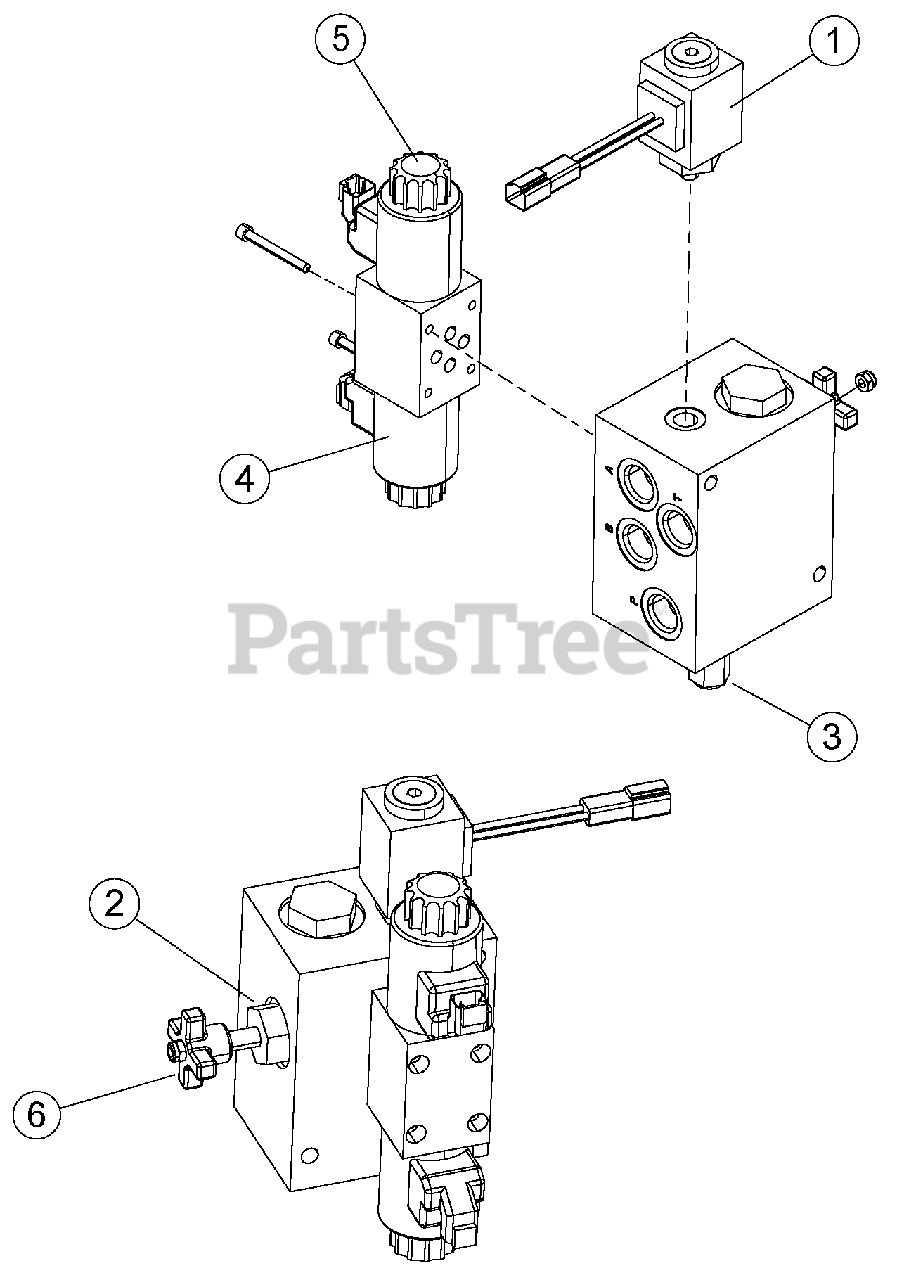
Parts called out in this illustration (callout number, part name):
1	HIGH PRESSURE SWITCH
2	VALVE, NEEDLE - 10 MOUNT
3	VALVE, DIFFERENTIAL SENSING
4	COIL SOLENOID
5	COIL NUT SOLENOID
6	KNOB VALVE
